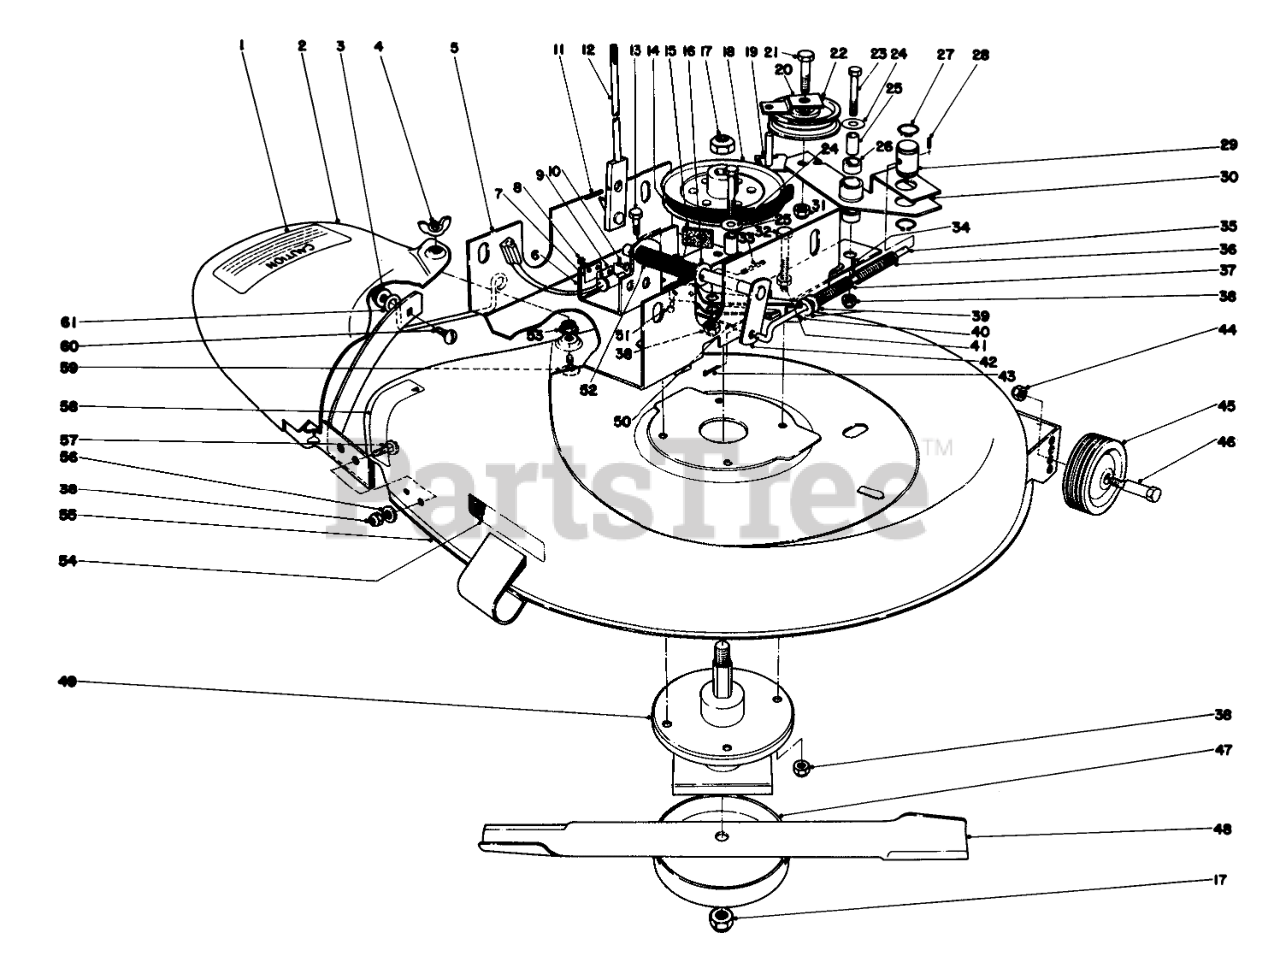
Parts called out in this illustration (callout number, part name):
1	Decal
2	DEFLECTOR WA R
3	NUT-LOCK, HHF
4	Wing Nut
5	CHANNEL HT ADJ R
6	Mounting Bracket Blade
7	Spacer Switch
8	NUT-KEPS
9	DECK INTERLOCK SWITCH
11	PIN-SPIRAL
12	Lever Deck Engagement
13	SCREW-HH
14	V-BELT
15	BLADE BRAKE LINING
16	WASHER-FLAT
18	DECK PULLEY R
19	Belt Retainer
20	Belt Retainer Upper
21	SCREW-HH
22	Flat Idler
23	SCREW-HH
24	WASHER-PLAIN
25	PIVOT SPACER
26	Bushing
27	RING-RETAINING
28	PIN-ROLL
29	Pin-Pivot
30	Idler Arm (Incl. Ref. #26)
31	NUT-LOCK, SIDE
32	SCREW-HH
33	PIN-SPRING
34	PIN-SPRING
35	BLADE ENGAGE ROD
36	Spring Deck Idler
37	Spring Deck Brake
38	NUT-LOCK, CONE
39	WASHER
40	Blade Brake (Incl. Ref. #15 & 51)
41	NUT-JAM
42	Linkage
43	PIN-COTTER
44	Nut
45	Wheel
47	Cup
48	Blade
49	Mower Spindle
50	Bracket Idler Mounting
51	Rivet
52	COMP SPRING O
53	PAL NUT
54	Decal-Deck Inst.
55	HOUSING WA R
56	WASHER-FLAT
57	BOLT-CARR
58	Decal Housing
59	Carriage Bolt
60	SCREW-CARRIAGE
61	Bracket Foot Guard
